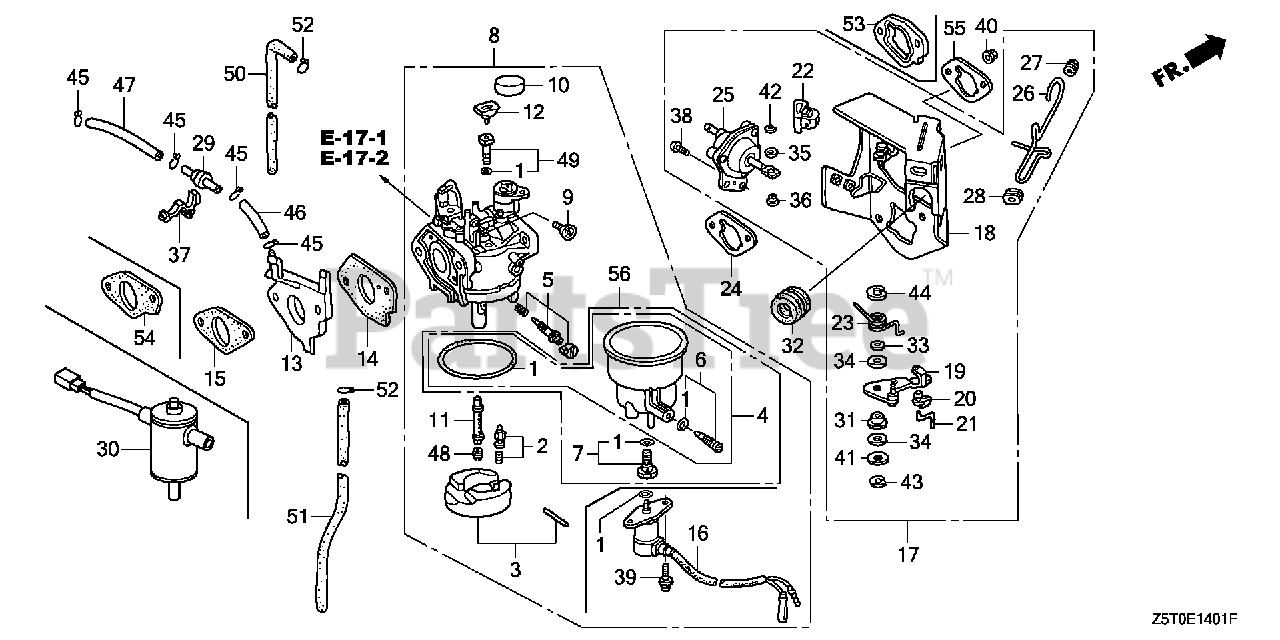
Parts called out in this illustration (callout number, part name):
1	GASKET SET
2	VALVE SET, FLOAT
3	FLOAT SET
4	CHAMBER SET, FLOAT
5	SCREW SET
6	SCREW SET, DRAIN (ADVENTURE GREEN) (CARBURETOR NO.)
7	SCREW SET B
8	CARBURETOR ASSY. (BE89E B)
9	SCREW, THROTTLE STOP
10	CAP, CHOKE LEVER DUST
11	NOZZLE, MAIN
12	COLLAR, SET
13	INSULATOR, CARBURETOR
14	GASKET, CARBURETOR
15	GASKET, INSULATOR Use up to Engine SN 2949254.
16	VALVE ASSY., SOLENOID
17	STAY ASSY., MANUAL CHOKE
18	STAY, SOLENOID
19	LEVER, CHOKE
20	JOINT, ROD
21	ROD, CHOKE
22	STOPPER, CHOKE ROD
23	SPRING, MANUAL CHOKE
24	GASKET, AIR CLEANER
25	DIAPHRAGM ASSY.
26	ROD, CHOKE CONTROL
27	GROMMET, CHOKE ROD
28	GUIDE, CHOKE ROD
29	VALVE, DASHPOT CHECK
30	VALVE ASSY., SOLENOID
31	BUSH, ARM PIVOT
32	GROMMET, FENDER
33	WASHER, CHOKE LEVER
34	SEAL, CHOKE LEVER
35	WASHER, THRUST (2.7X8)
36	COLLAR, LEVER
38	SCREW, PAN (5X12)
39	SCREW-WASHER (5X12)
40	NUT, FLANGE (6MM)
41	WASHER, PLAIN (5MM)
42	E-RING (2MM)
43	E-RING (4MM)
44	E-RING (7MM)
45	CLIP, TUBE (B7)
46	BULK HOSE, VACUUM (3.5X8000) (3.5X130)
47	BULK HOSE, VACUUM (3.5X8000) (3.5X130)
48	JET, MAIN (#98) Use from Engine SN BE87A A to BE87A A.
48	JET, MAIN (#100) Use from Engine SN BE87A A to BE87A A.
48	JET, MAIN (#102) (ADVENTURE GREEN) (CARBURETOR NO.)
49	JET SET, PILOT (#45)
55	GASKET, AIR CLEANER
